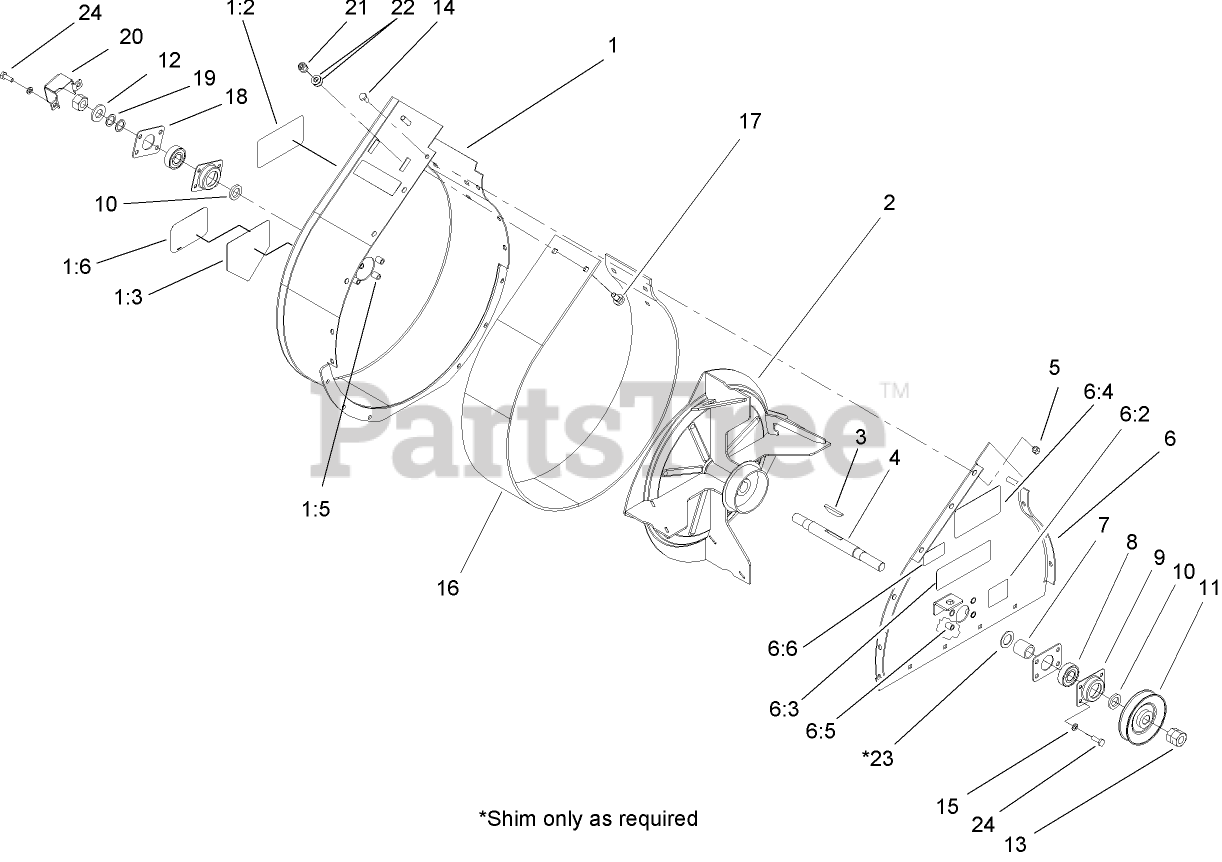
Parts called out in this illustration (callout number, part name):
1	BLOWER HOUSING ASM
1:2	DECAL-DANGER
1:3	DECAL-DANGER
1:5	INSERT-NUT
1:6	DECAL
2	IMPELLER ASM
4	Shaft-Blower
5	NUT-LOCK, NI
6	COVER PLATE ASM
6:2	DECAL-WARNING
6:3	DECAL-DANGER
6:4	DECAL-DANGER
6:5	INSERT-NUT
6:6	DECAL-PROTECTION, EAR
7	Spacer
8	BEARING-BALL
9	CUP-BEARING
10	SPACER-BEARING
11	Pulley ASM
12	WASHER-FLAT
13	NUT-HEX
14	SCREW-HH
15	WASHER-LOCK
16	STRIP-WEAR
17	BOLT-CARR
18	PLATE-COVER
19	WASHER-FLAT
20	Cover-Shaft
21	NUT-LOCK, NI
22	WASHER-PLAIN
23	WASHER-THRUST
24	SCREW-HH
